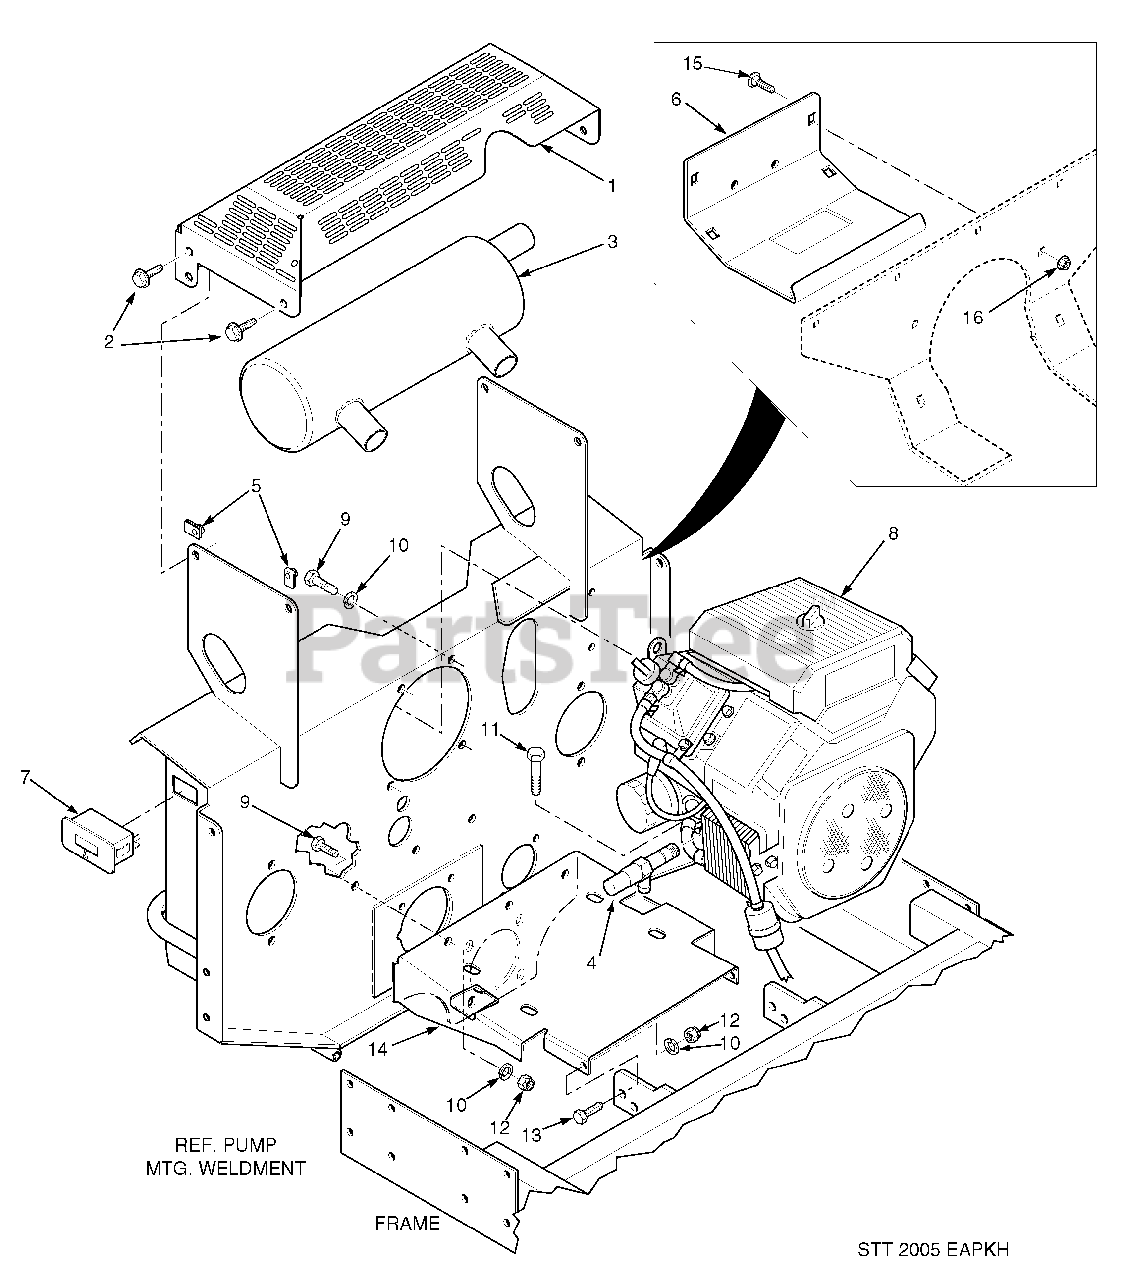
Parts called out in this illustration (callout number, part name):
1	Muffler Guard
2	Screw, Hex Serrated Flange 1/4-20 x 3/4"
3	Muffler, Part Of Engine
4	Oil Drain Extension
5	U-Nut, 1/4-20
6	Rear Cover
7	Hour Meter
8	Engine, Kohler 27 CH
9	Bolt, Hex Head 3/8-16 x 1"
10	Lockwasher, 3/8" Spring
11	Bolt, Hex Head 3/8-16 x 1-3/4"
12	Nut, Hex Elastic Stop 3/8-16
13	Bolt, Hex Head 3/8-16 x 1-1/4"
14	Plate, Engine Mounting
15	Bolt, Carriage 5/16-18 x 3/4"
16	Nut, Hex Serrated Flange 5/16-18
